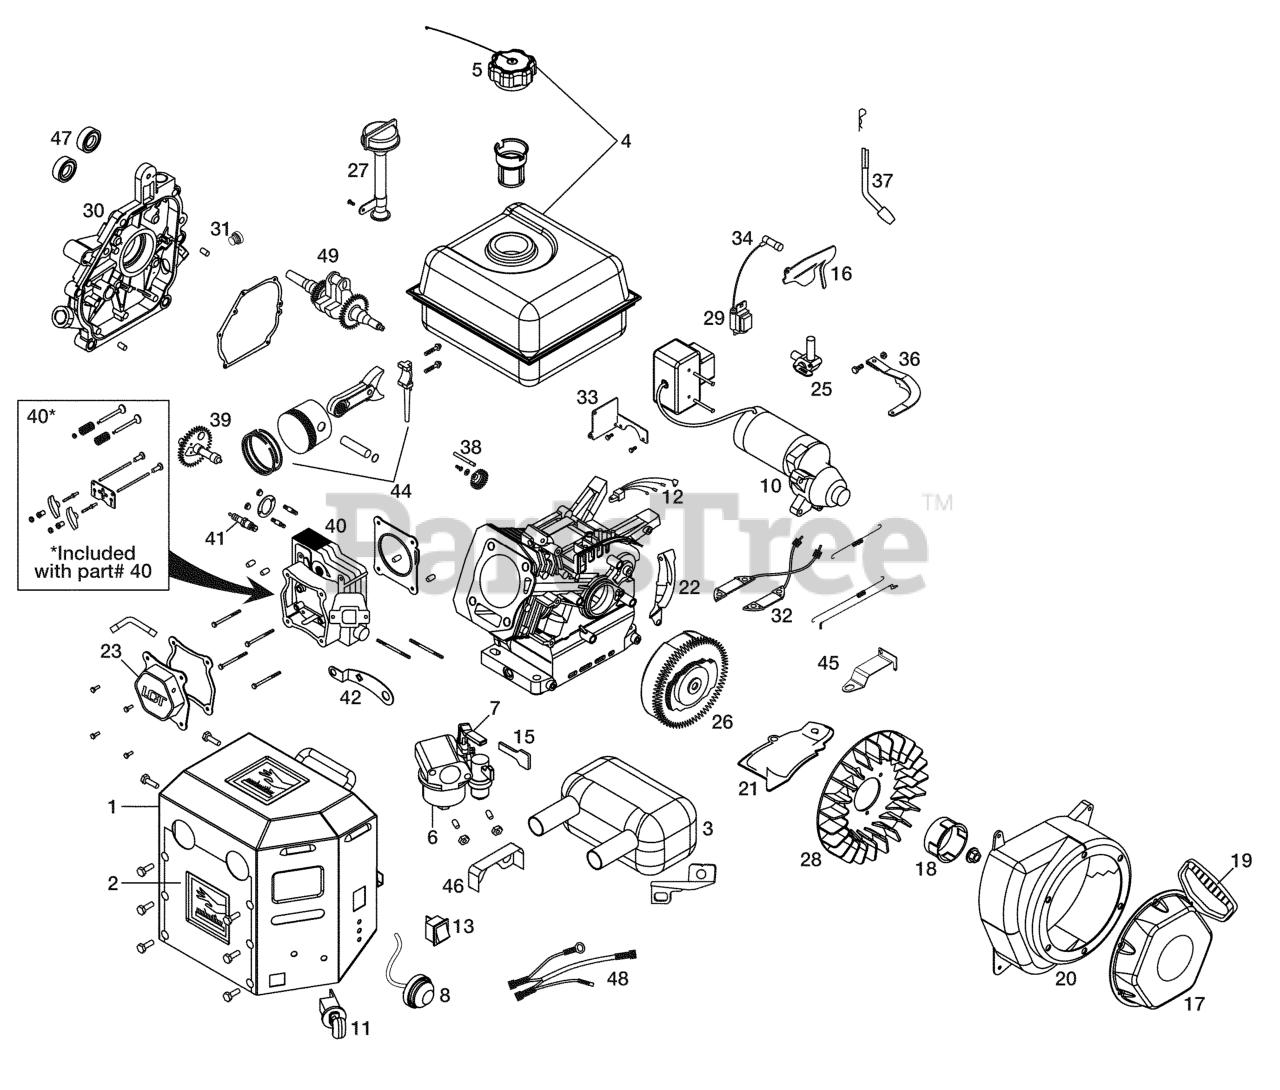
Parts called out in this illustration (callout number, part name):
1	ASSY.SNOW.HEATER.BOX(SKSN-010
2	KIT.FASTENER.HEATER(SKSN-0101)
3	ASSY.SNOW.MUFFLER(SKSN-0200)
4	ASSY.SNOW.FUEL.TANK(SKSN-0300)
5	FUEL CAP OVERSIZED CLICK STYLE
6	ASSY.SNOW.CARB(SKSN-0302)
7	RP SNOW.CHOKE.LVR.CARB
8	PRIMER.BULB.WITH HOSE (SNOW)
10	ASSY.ELECT.STARTER(SKSN-0400)
11	SWITH.KEY.ASSEM.SNOW.SINGLE.ST
12	CDI.BOX SNOW
13	SWITCH.ON/OFF(SKSN-0403)
15	THROT/CHOKE.HND(RED)(SKSN-0500
16	GOVERNOR.LINK.SHIELD PLATE
17	RECOIL.ASSY(HEX-BLACK)SNOW
18	STARTER.CUP.SMALL(SKSN-0601.1)
19	STARTER.GRIP.SNOW.LCT.SKSN0603
20	BLOW.HSG.ASSY.ELEC(SKSN-0602)
20A	BLOW.HSG.ASSY.ELEC(SKSN-0612)
21	SHILED.FLYWEEL.SYS(SKSN-0604)
22	SHLD.ELEC.START.FLY(SKSN-0605)
23	VALVE COVER ASSEMBLY
25	FUEL.PETCOCK.LQA.3/16".LCT
26	ELECT.FLYWHEEL.ASSY(SKSN-0405)
26A	FLYWHL.ASSY.MANUL.SK2081700
27	HIGH OIL FILL DIPSTICK ASSEM
28	FLYWHEEL FAN 420586
29	KIT.IGNITION.COIL
30	CRANKCASE COVER ASSY
31	DIPSTICK SMALL
32	CHARGING.COIL(ELEC)SKSN0406.1
33	ELECTRIC.START.BRKT(SKSN0606)
34	SPARK.PLUG.BOOT(SK2083800)
36	RP_IT.GOVERNOR.ARM(SUMMER ENG)
37	KIT.GOVERNOR.CRANK(SK208-3100)
38	THROTTLE CONTROL ASSEM
39	KIT.CAMSHAFT.208CC.LCT
40	CYLINDR.HEAD.SRV.KIT W/GASKET
41	SPARK.PLUG(2083810)
42	CDI.BOX.BRACKET SNOW
44	KIT.PISTON.SRV(SK208-1400)
45	SPEED.CTRL.BRKT.(SKSN0150)
46	SHIELD.VAPOR.SNOW
47	OIL.SHIELD.KIT
48	WIRE.HARNESS.SNOW
49	CRANKSHAFT-KEYED
